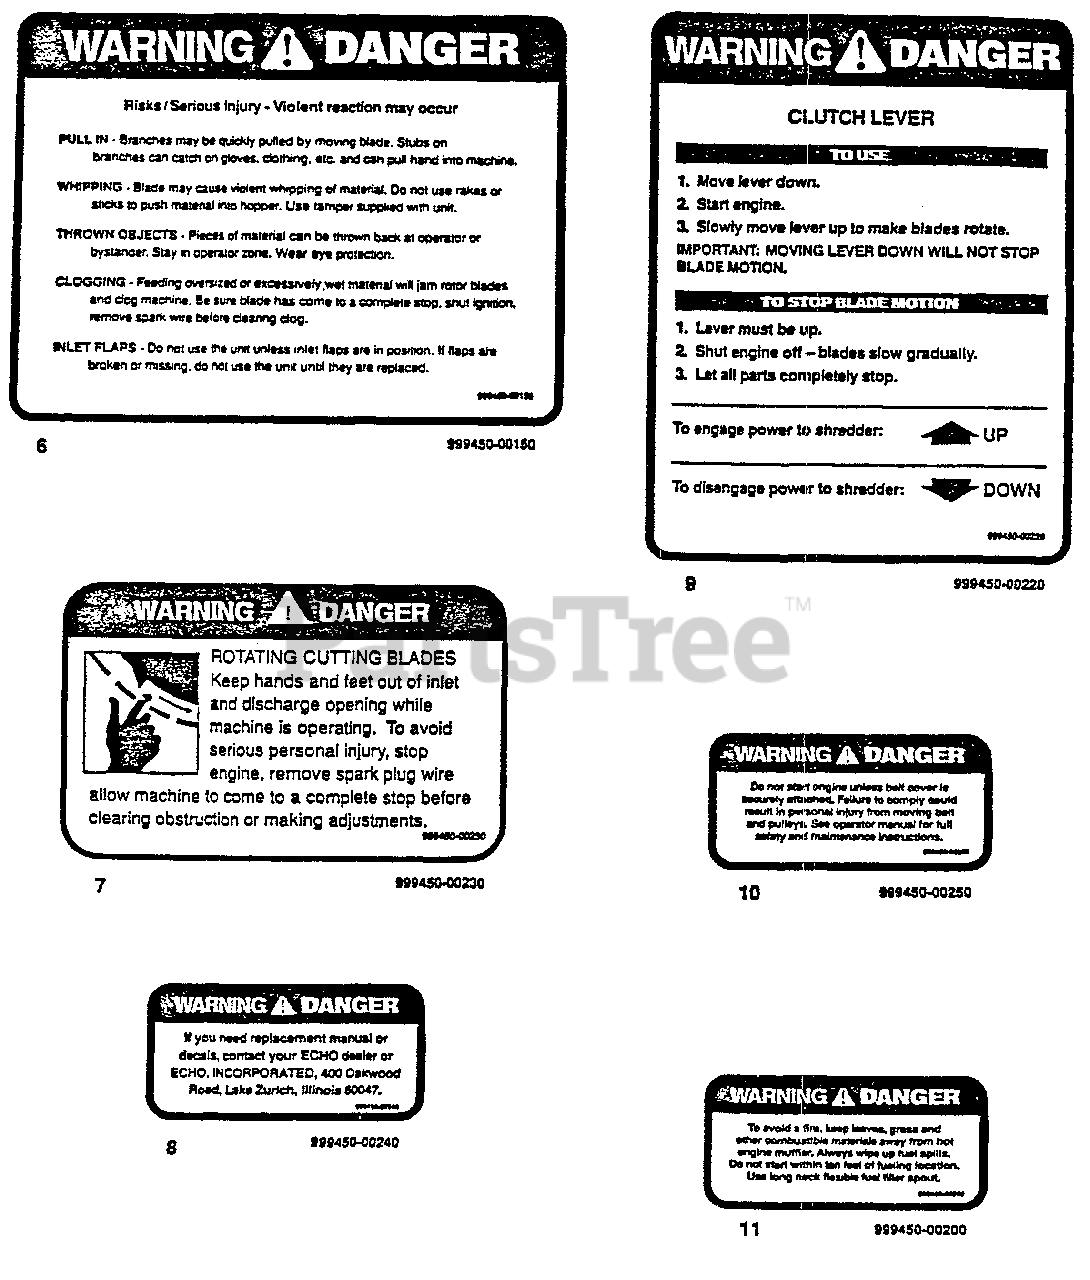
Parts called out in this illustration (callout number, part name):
6	LABEL
7	LABEL
9	LABEL
10	LABEL
11	LABEL
